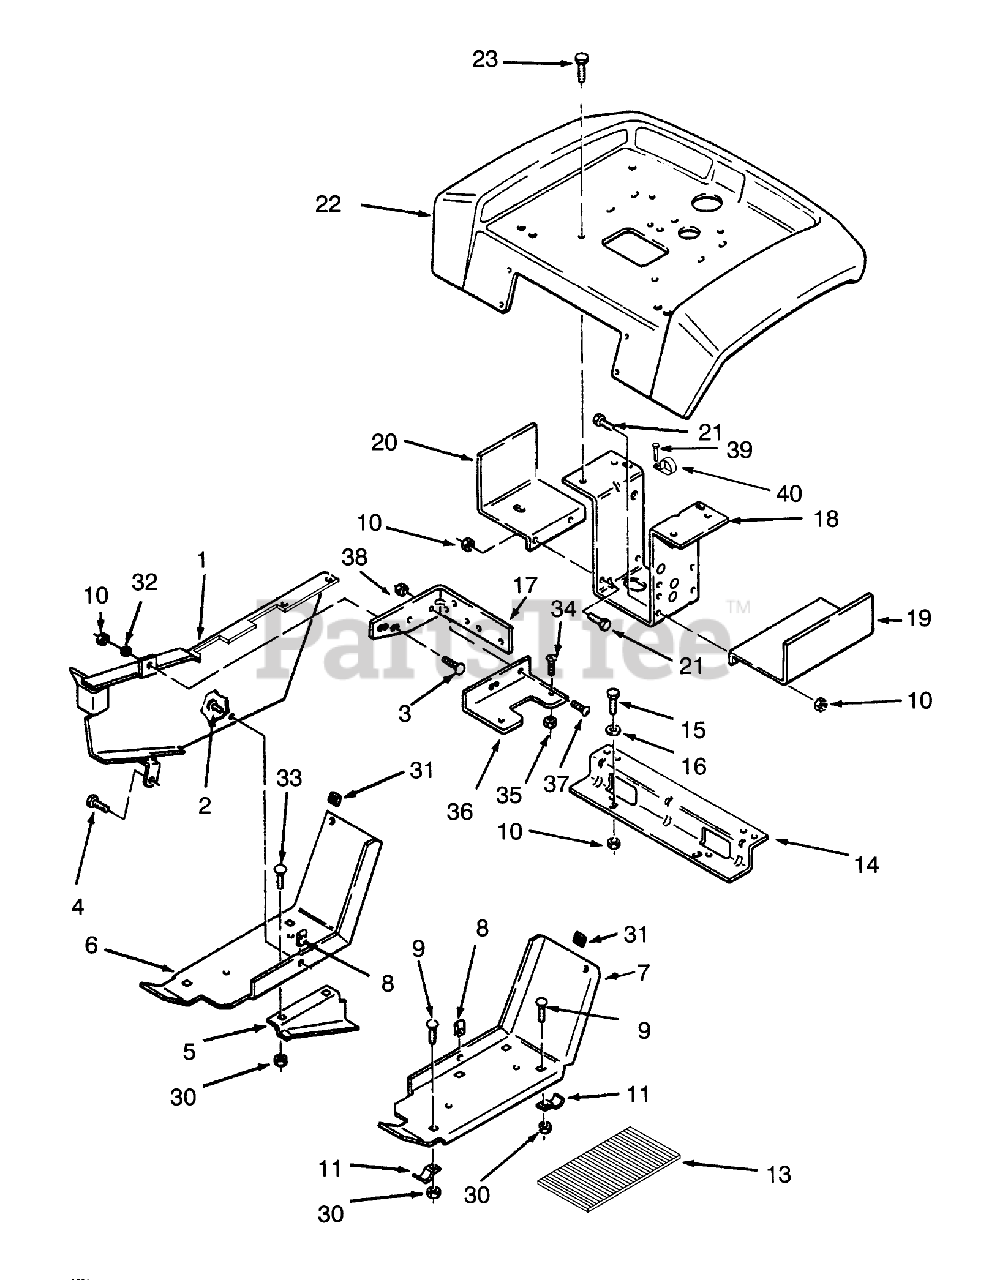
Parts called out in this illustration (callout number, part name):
2	SCREW-PPH
3	BOLT-CARR
7	FOOTREST LH *R
9	BOLT-CARR
10	NUT-LOCK, NI
11	BRACKET
13	PAD FOOTREST
15	SCREW-HH
16	WASHER-PLAIN
17	BRACKET-BELT*B
21	SCREW-HH
30	NUT-LOCK, NI
31	BUMPER SJ5514 BLACK
34	SCREW-PAN
36	BRKT-FUS HLDER*B
37	SCREW-HH
38	NUT-LOCK, NI
39	SCREW-HH, LOCK
40	CLIP
